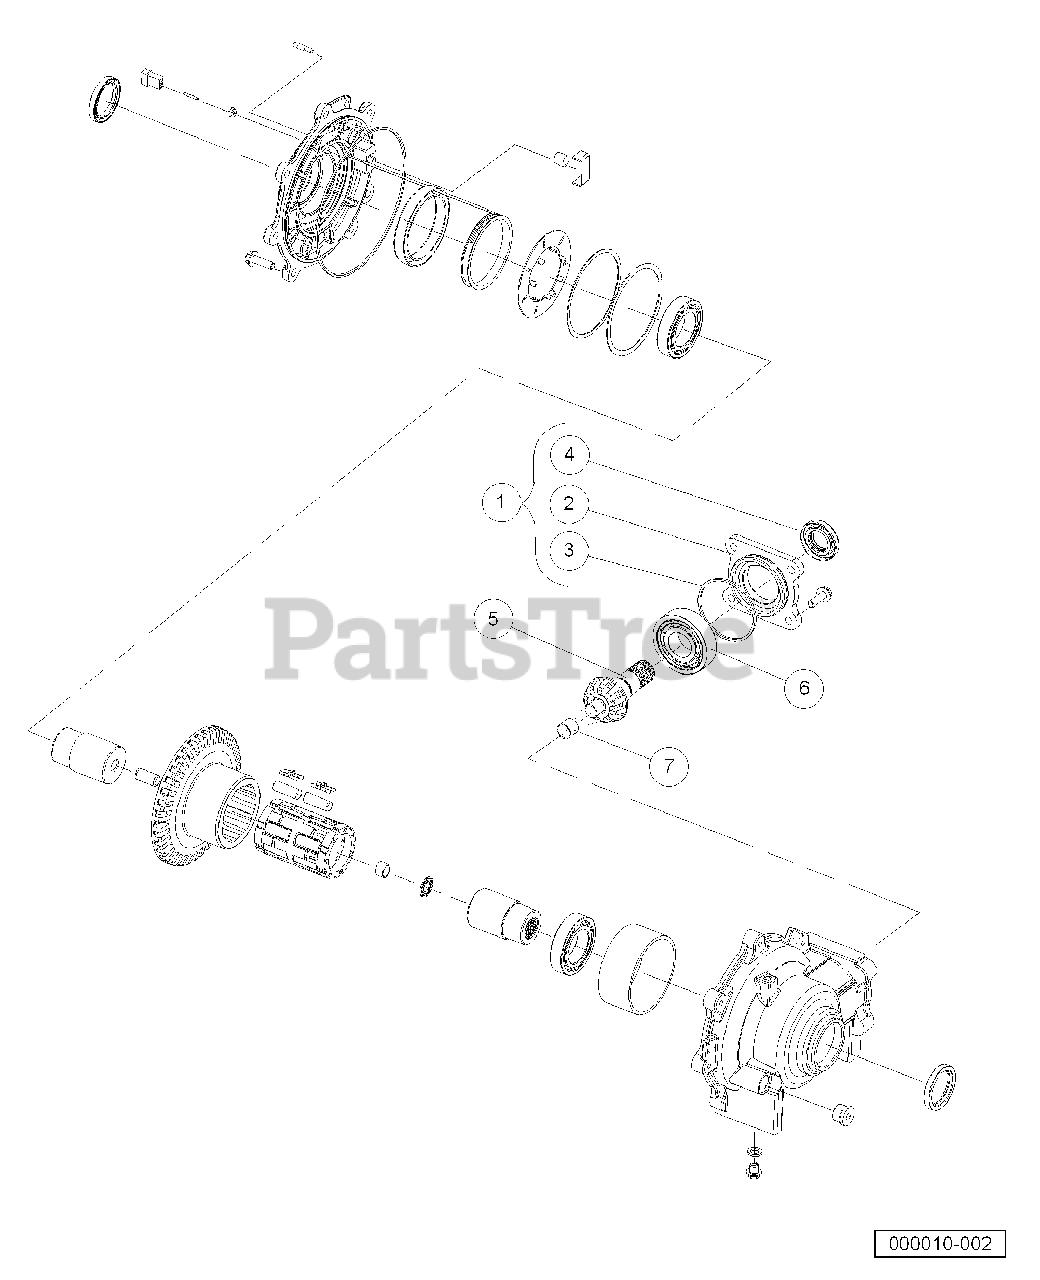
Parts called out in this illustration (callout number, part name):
1	Kit, Assy, Input Cover Plate
2	Cover, Input, Machined
3	O-Ring
4	Oil Seal, Triple-Lipped
5	Shaft, Pinion, Machined
6	Bearing, Ball
7	Bushing, Plain 16 Id X 15 Wide
